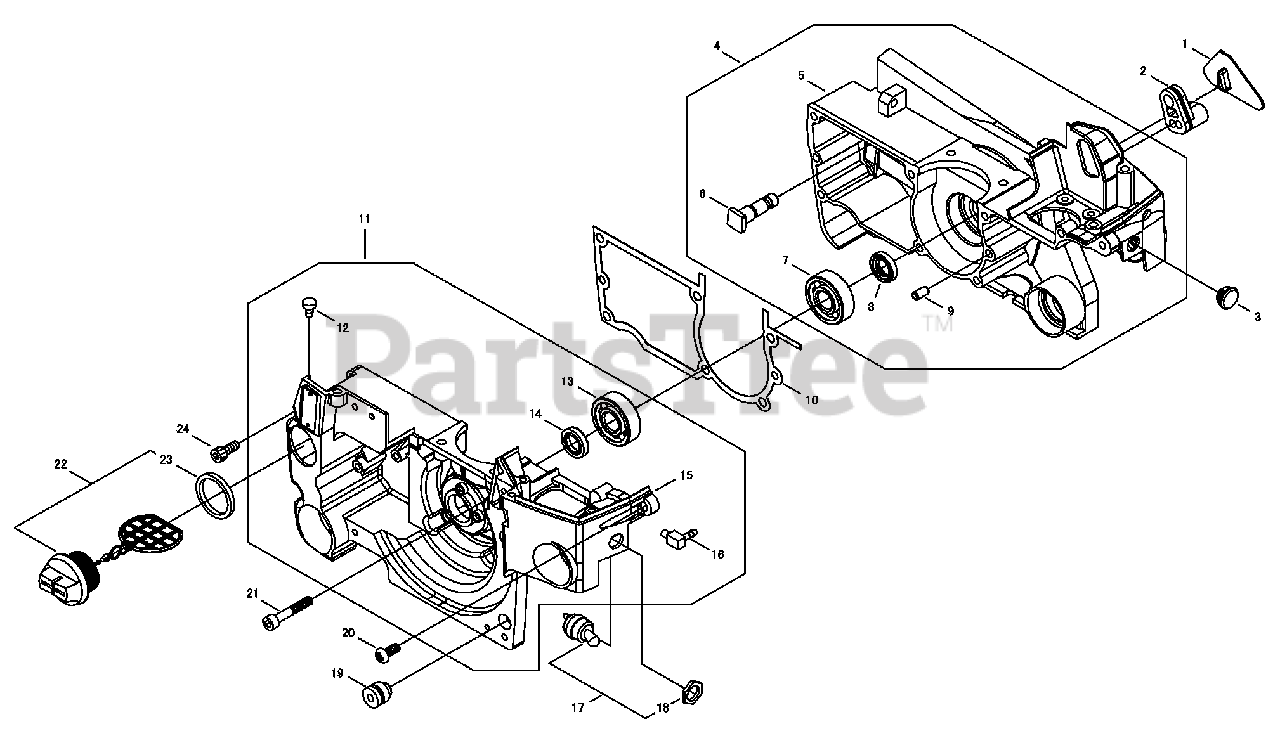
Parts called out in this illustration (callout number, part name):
1	STOPPER H
2	GROMMET
3	PLUG
4	CRANKCASE ASSY - RIGHT
5	CRANKCASE - RIGHT
6	STUD, GUIDE BAR
7	BEARING, BALL - 6001
8	SEAL, OIL - 12
9	PIN - LOCATING
10	GASKET, CRANKCASE
11	CRANKCASE ASSY - LEFT
12	VALVE, CHECK
13	BEARING, BALL - 6001
14	SEAL, OIL - 12
15	CRANKCASE - LEFT
16	CONNECTOR, PIPE
17	IGNITION SWITCH ASSY
18	NUT - 10
19	SUPPORTER
20	SCREW
21	BOLT
22	CAP ASSY
23	GASKET, CAP
24	BOLT
